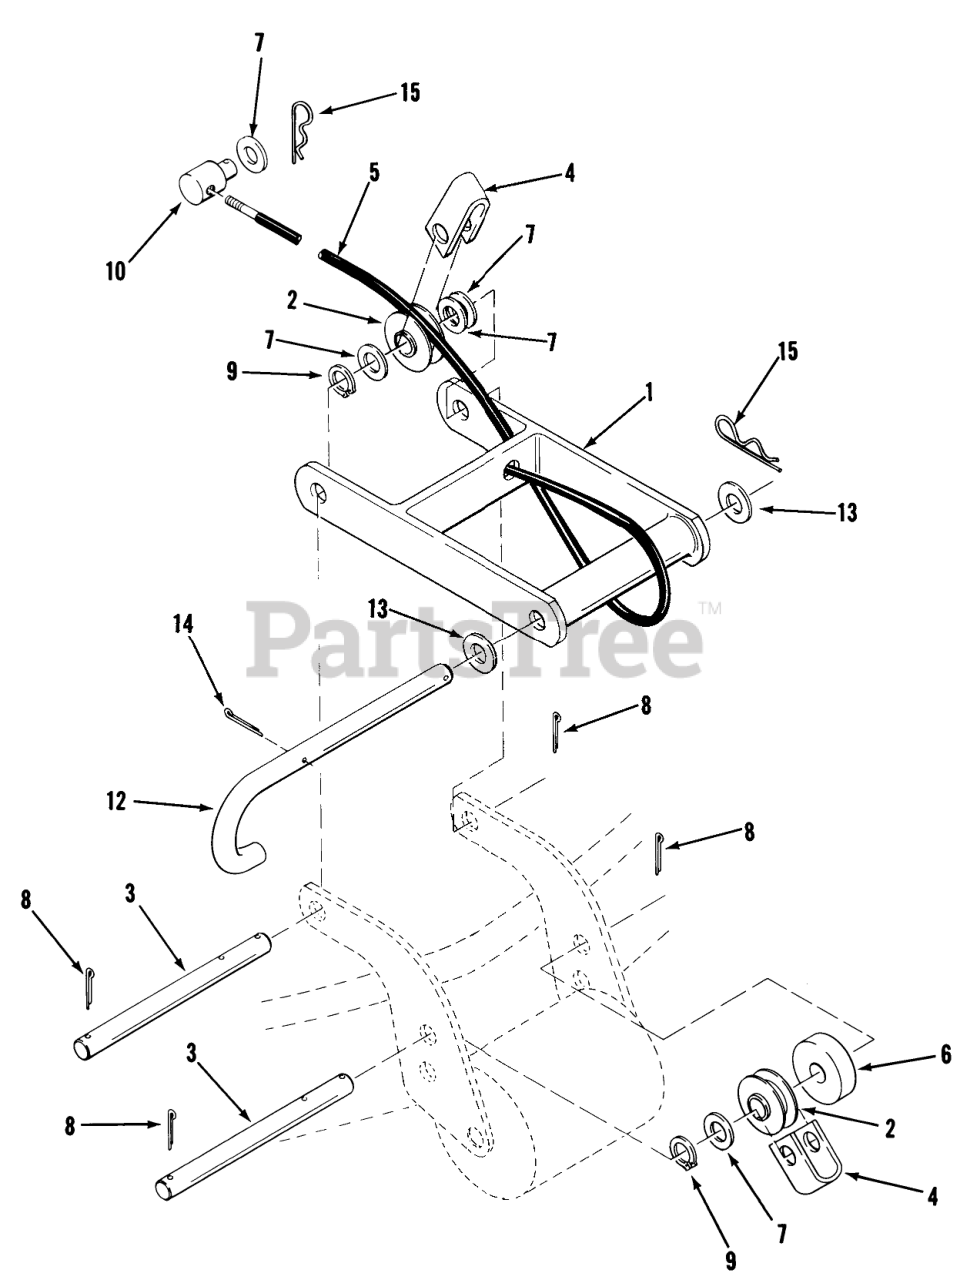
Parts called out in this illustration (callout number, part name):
1	Front Mount
2	ROLLER-CABLE
3	Rod
4	STRAP-CABLE
5	ASSY-CABLE
6	SPACER
7	Washer
8	Pop Rivet
9	GRIP RING
10	TRUNNION-CLUTCH ROD
12	"J" Pin
13	Washer
15	Hairpin Cotter
